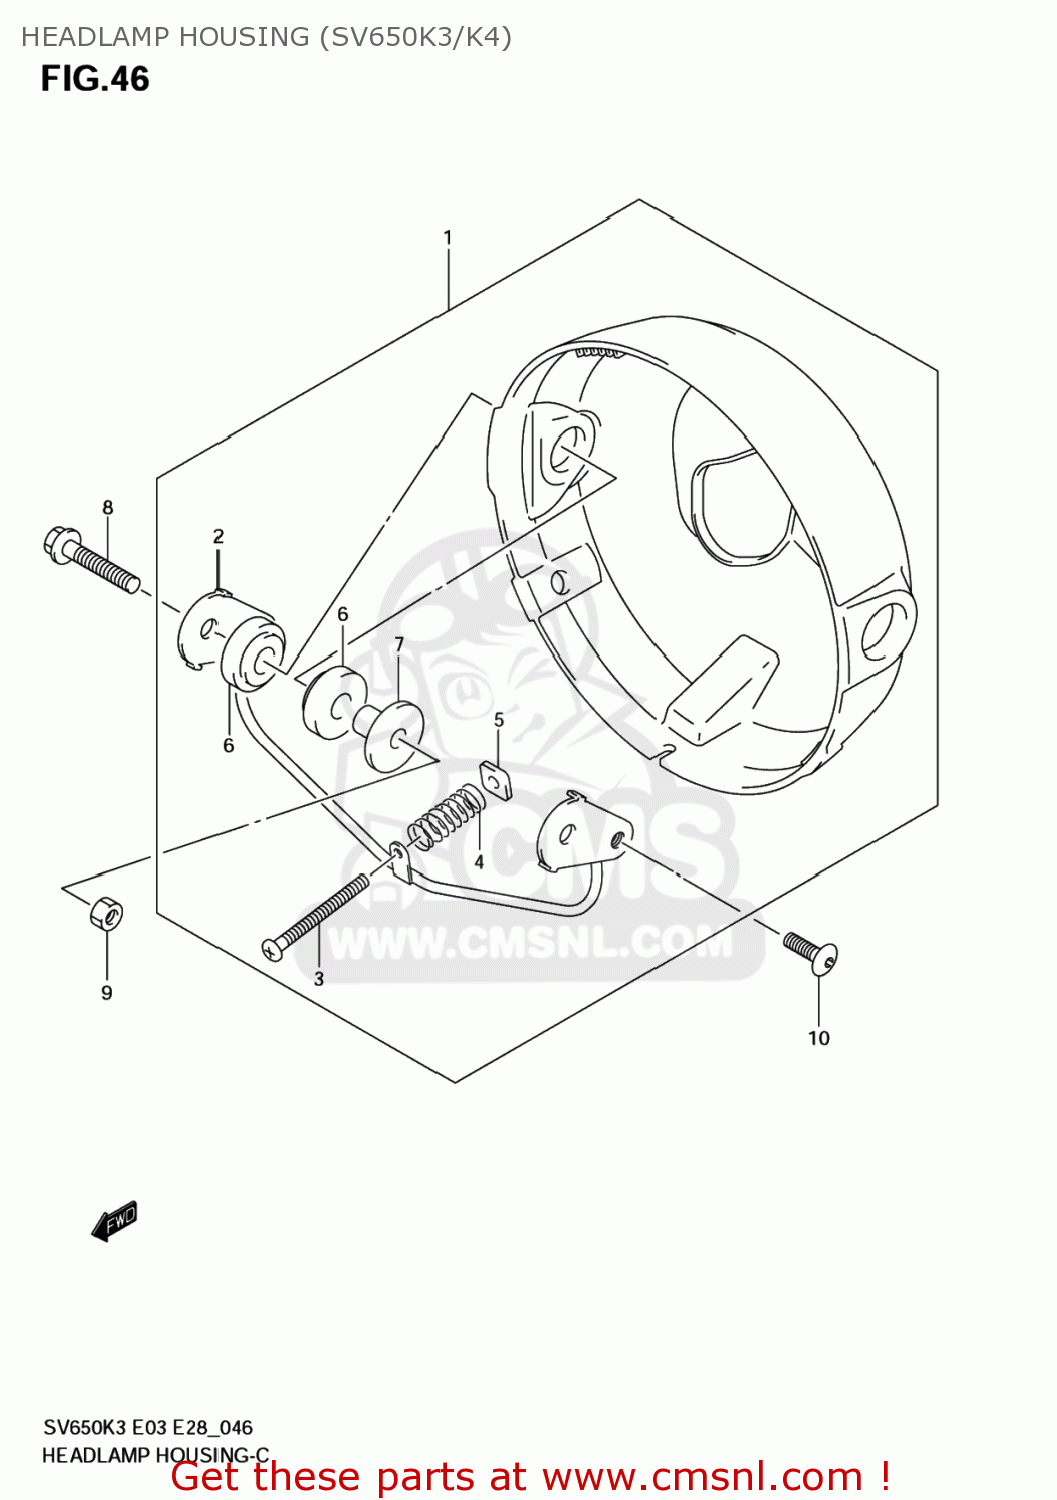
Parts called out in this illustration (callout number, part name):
1	HOUSING ASSY,HEADLAMP
2	PLATE,HEADLAMP HOUSING
3	SCREW(5X45)
4	SPRING,HEADLAMP ADJUSTER
5	NUT,HEADLAMP ADJUSTER
6	CUSHION
7	SPACER(8.6X12X21.3)
8	BOLT(8X35)
9	NUT
10	SCREW(6X16)
